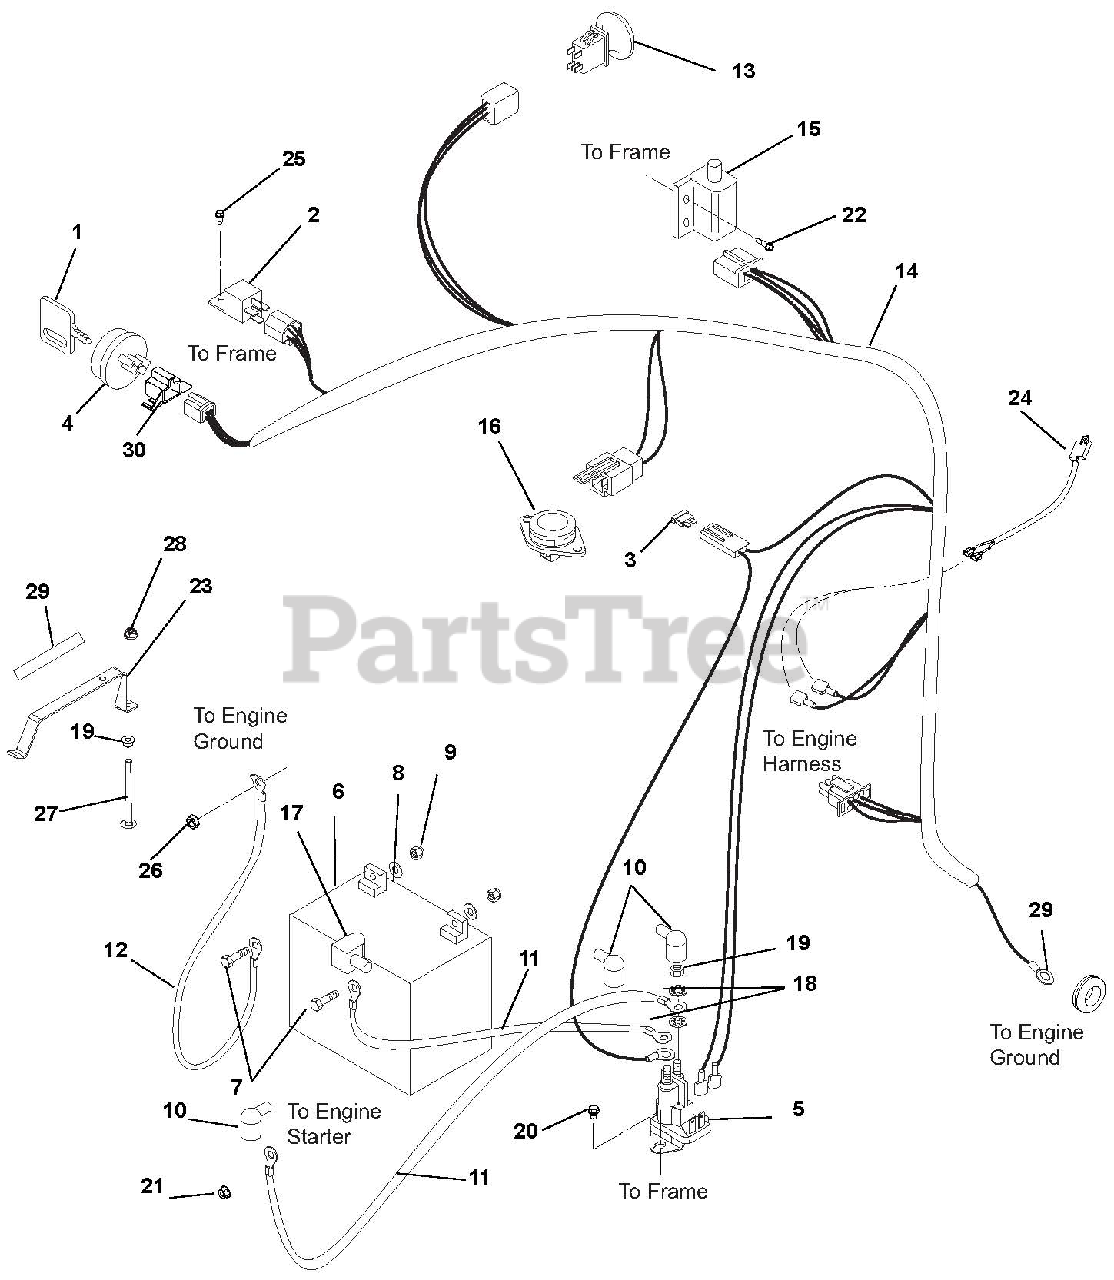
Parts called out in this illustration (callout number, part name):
1	Key
1	Key- with Cap
2	Relay
3	Fuse, 30 AMP
4	KEYSWITCH-IGNITION 3 POS
4	Key Switch
5	Solenoid
6	Battery, 12V 12A
7	Bolt, Hex .25-20 x .75
8	Washer, Flat Steel .281 x .62 x .065
9	Nut, KEPS .250-20
10	Boot, Eyelet Terminal
11	Cable, POS
12	Ground Cable
13	Switch, Clutch With Retainer
14	Harness, Wiring Zoom
15	Switch, Double Pole N.O. / N.O.
16	Switch, Snap Mounting N.O.
17	Insulator
18	Washer, Locking .31
19	Nut-Hex M6x1.0
20	Screw, Tapping .250-20 x .37 Hex Washer Head
21	Nut, Locking Top Flange .25-20
22	Screw, 12-14 x .75 HX
23	Hold Down, Battery
24	Harness, Clutch
25	Screw, Tapping 10-24 x .50 HWH TR YWZC
26	Nut, Locking Center Jam .375-16
27	Bolt, Round Head Square Neck .25-20 x 4.50
28	Nut, Locking Nylon Flange .25-20
29	Cable Tie
30	Wire Harness, Key Switch ADAPT
